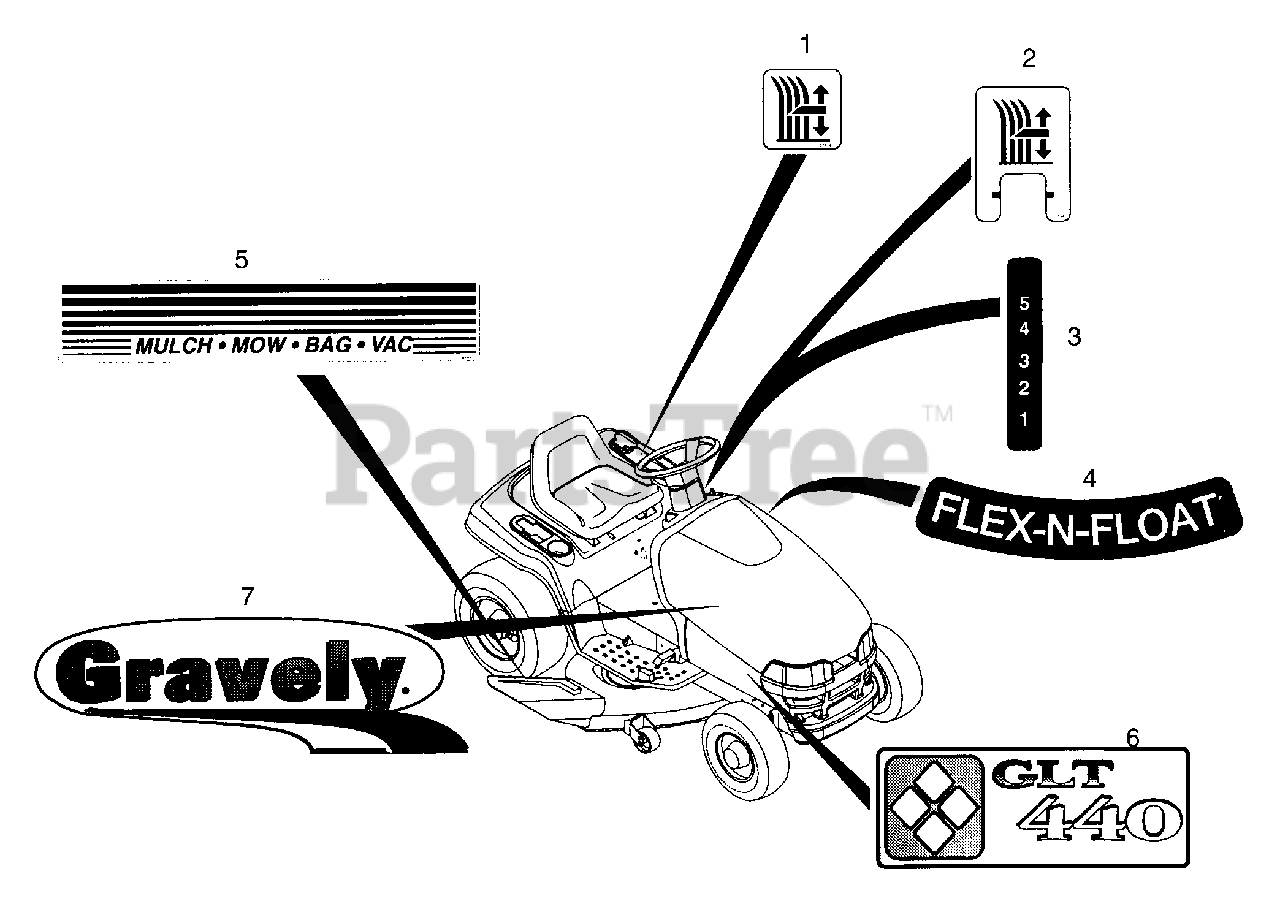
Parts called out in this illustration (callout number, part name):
1	Decal-Cut Height-Insert
2	Decal-Cut Height-Frame
3	Decal-Indicator 5 Pos
4	Decal-Flex-N-Float
5	Decal-Mulch-Mow-Bag-Vac
6	Decal-GLT 440-Kohler
6	Decal-GLT 440-B&S
6	Decal-GLT 448
7	Decal-Logo-GLT-Right Hand
7	Decal-Logo-GLT-Left Hand
